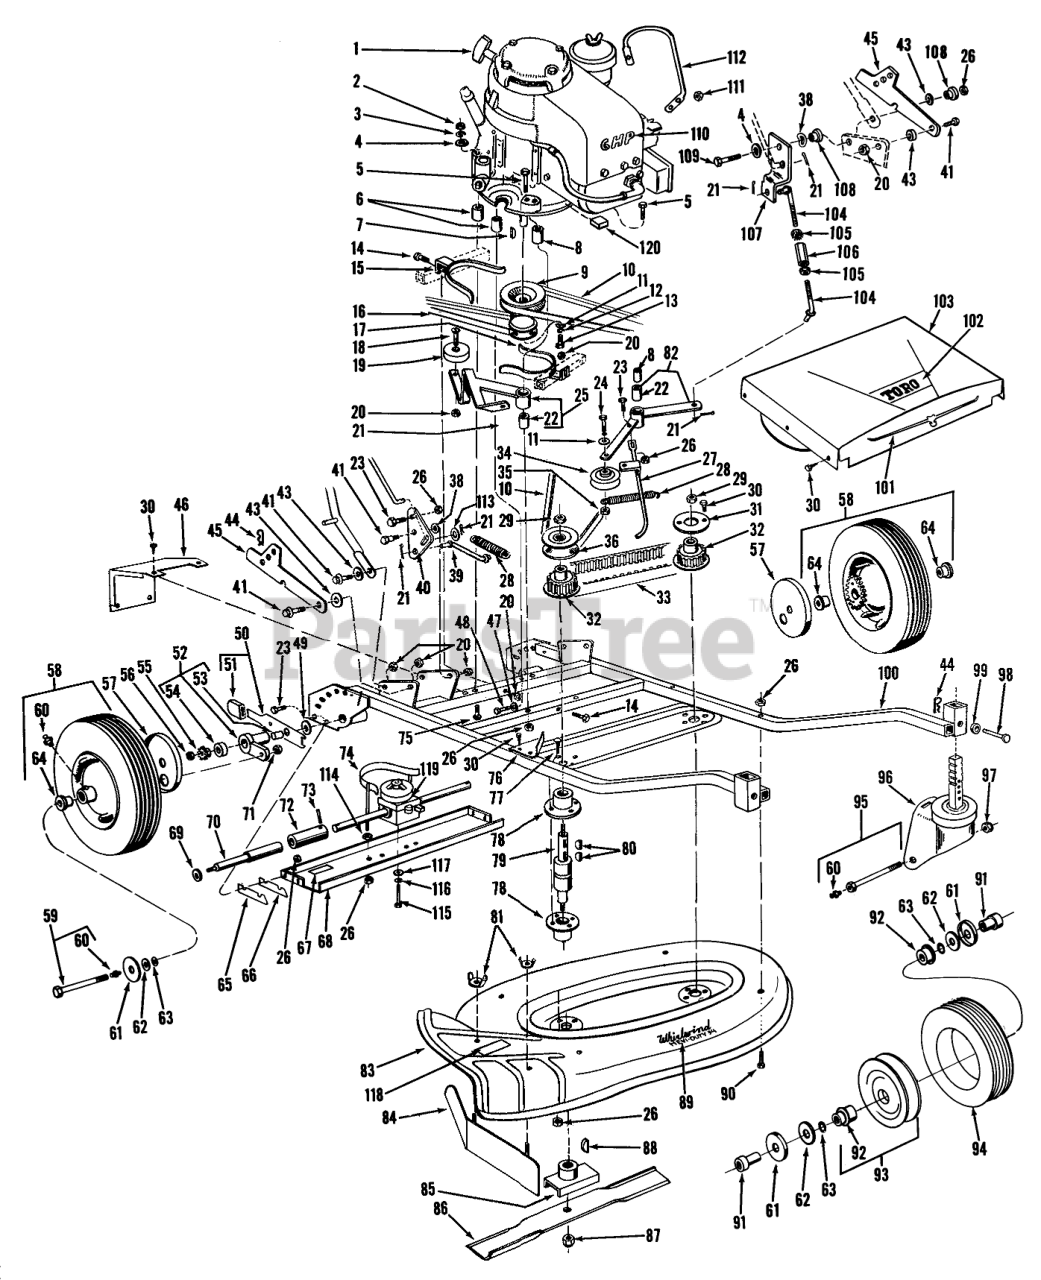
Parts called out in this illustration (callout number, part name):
1	Engine
2	NUT-HEX
3	WASHER-LOCK
4	WASHER-PLAIN
5	SCREW-HH
6	Spacer
7	KEY-WOODRUFF
8	ENGINE PIVOT SPACER
9	Pulley
10	CUTTER BELT
11	WASHER-FLAT
12	WASHER-LOCK
13	SCREW-HH
14	SCREW-HH
15	Retainer, Belt
17	Retainer Belt
18	Flat Head Screw
19	PULLEY B
20	NUT-LOCK, NI
21	PIN-COTTER
22	BUSHING
23	SCREW-HH
24	Screw
25	Idler Arm
26	NUT-LOCK, NI
27	Brake Arm
28	EXTENSION SPRING
29	NUT-LOCK, NI
30	10-16 X 3/8 THDG SCREW
31	Belt Guide
32	Pulley
34	IDLER PULLEY R
35	NUT-LOCK
36	Pulley
38	WASHER
40	Bellcrank
41	Screw
42	Lower Handle Assy.
43	SPACER
44	PIN-COTTER
45	Latch
46	Rear Shroud
48	SCREW-HH
49	WASHER
52	Pivot Arm
53	BUSHING
54	.375 RPP BALL BEARING
55	Pinion Kit
56	NUT-HJ
57	Wheel Cover
58	Rear Wheel Assy.
59	Axle Bolt Use on Serial No. 1 thru 250
59	SCREW-HH
60	FITTING-GREASE
61	SLINGER
62	Washer
63	O-RING
64	BEARING-BALL
64	BEARING
65	Shim .015
66	Shim .030
67	Serial Name Plate
68	Support
69	Washer
70	Drive Spindle
71	NUT-LOCK, NI
72	Clutch Assembly
73	Groove Pin
74	Belt Band
76	Belt Retainer
77	Bolt
78	Bearing Housing
79	Bearing, Spindle
80	KEY-WOODRUFF
81	NUT-WING SPECL
82	Arm & Bushing Assembly
83	Housing
84	Leaf Mulcher
85	BLADE RETAINER WA
86	18 BLADE
87	NUT-LOCK
88	3/32X5/8 WOODRUFF KEY
89	Decal
91	Spacer
93	Wheel W.A. w/Ref. No. 53
94	1.75-8 SEMIPNEU TIRE
95	Axle Bolt w/Zerk
96	Caster
97	NUT-LOCK, NI
99	Grommet
100	Frame
101	Decal
102	Decal
103	Shroud
105	NUT-KEPS
106	CONTROL ROD SLEEVE
107	Bell Crank
108	PIVOT
109	SCREW-HWH, THREAD CUT
110	Decal
111	NUT-LOCK
113	Spacer
114	NUT-JAM
115	SCREW-HH
116	WASHER-FLAT
117	WASHER-LOCK
118	Decal
119	Transmission Assembly
120	Spacer
